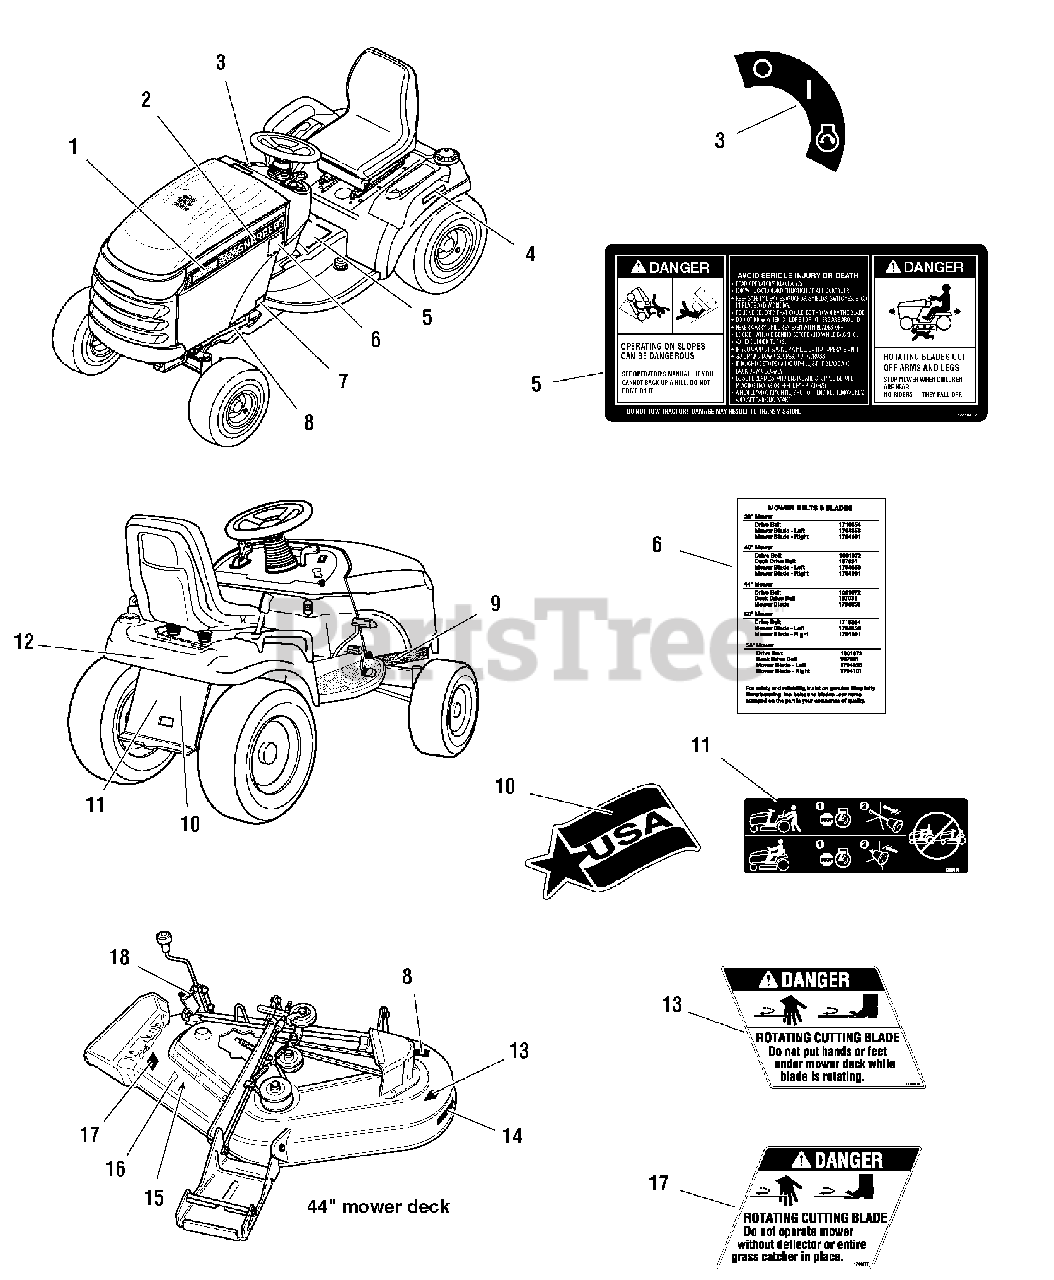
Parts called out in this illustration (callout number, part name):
1	DECAL, LT1644
2	DECAL, Hood Stripe, Snapper, LH
2	DECAL, Hood Stripe, Snapper, RH
3	DECAL, Ignition Switch Symbols, White/Black
4	DECAL, Automatic Control Traction
5	DECAL, Tunnel Cover, Danger Slopes/Blades
6	DECAL, Drive Belts & Mower Blades
7	DECAL, Protective Sticker
8	* DECAL, I.D. Plate
9	* DECAL, Patent
10	DECAL, USA Logo Stars & Stripe
11	DECAL, Transmission Release Valve
12	DECAL, Snapper
13	DECAL, Danger Do Not Put Hands/Feet in Mower
14	DECAL, Free Floating Mower, Silver
15	* DECAL, OPEI Certified
16	DECAL, 44", Silver on Black with Stripe
17	DECAL, Danger Do Not Operate Without Deflector
18	DECAL, Height of Cut, 38" & 44"
